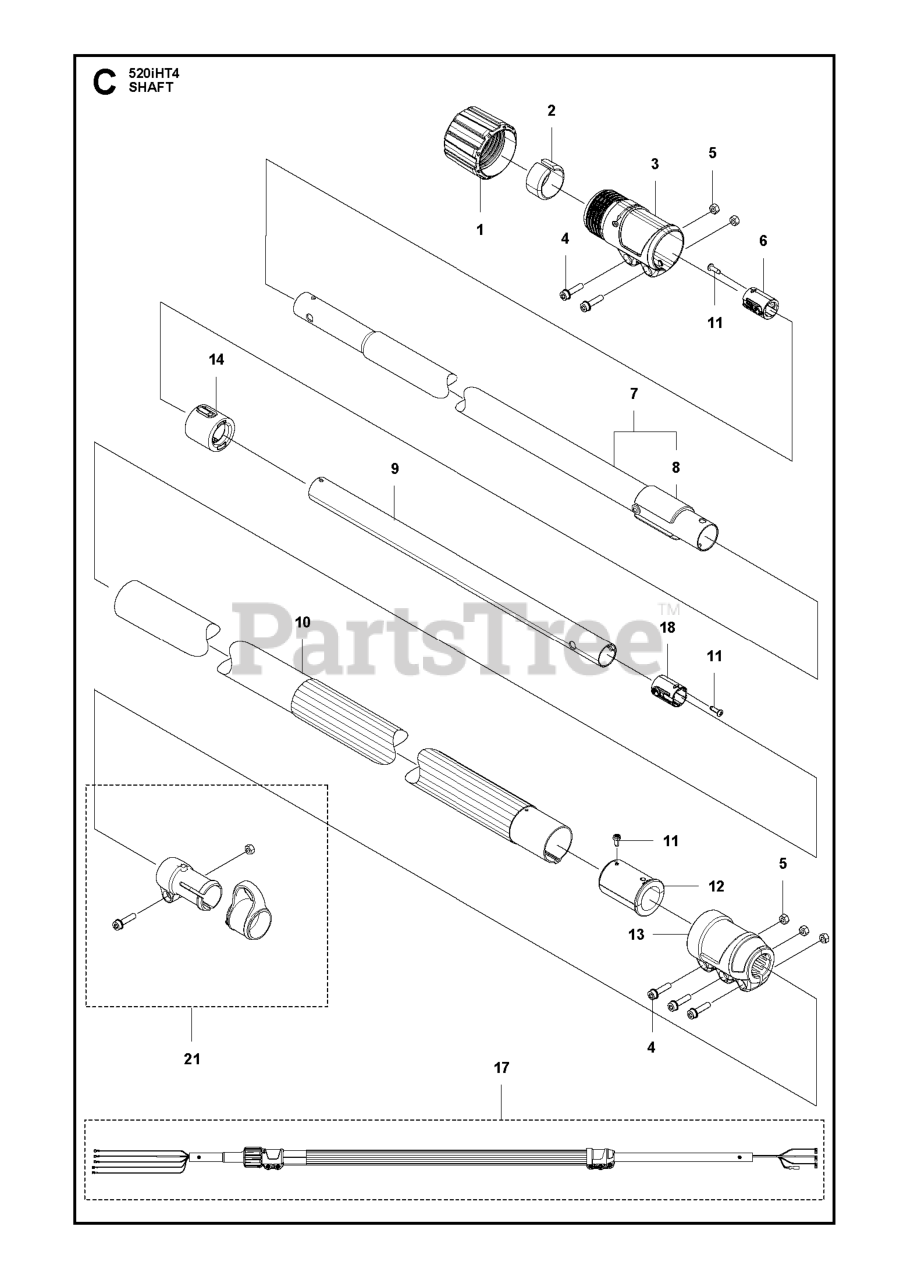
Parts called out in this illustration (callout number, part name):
3	CLAMPING SLEEVE
6	SPACER CABLELOCK
8	GUIDE BUSHING
11	SCREW
13	CLAMPING SLEEVE
17	TUBE ASSY TELESCOPIC POLE HT
21	CORD BRACKET CPL BATTERY POLE
